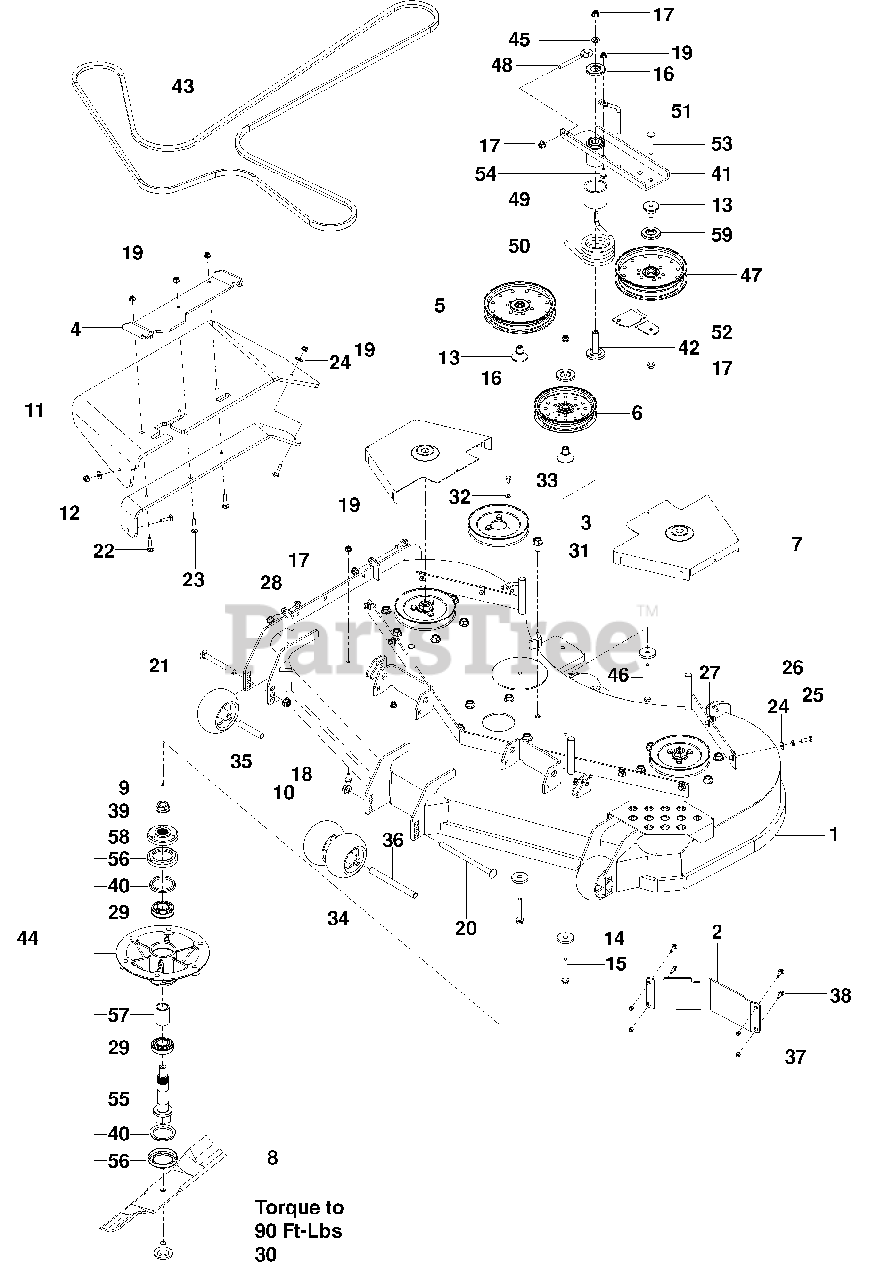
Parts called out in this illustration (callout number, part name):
1	DECK w/ SAFETY DECALS
2	BAFFLE, FLOW DIVERTER
4	BRACKET, CHUTE PIVOT BLK
5	PULLEY, IDLER 7" NARROW
6	PULLEY, IDLER, 6"
7	SHIELD, BELT
8	BLADE, 21"
9	ZERK
10	NUT 1/2-13 HEX FLG NYLOC
11	CHUTE, DISCHARGE
12	BRACKET, CHUTE SUPPORT
13	BEARING, IDLER ARM
14	WASHER, HEAVY
15	SCREW 3/8-16 x 2 3/4 HEX FLG
16	SHIELD, DUST
17	NUT 3/8-16 HEX FLG NYLOC
18	HHFS 5/16-18 x 3/4
19	NUT 5/16-18 HEX FLANGE NYLOC
20	BOLT 1/2-13 x 8 RD HD
21	BOLT 1/2-13 x 4 3/4 RD HD
22	BOLT 5/16-18 x 1 1/2 RD HD
23	BOLT 5/16-18 x 1 1/4 RD HD
24	WASHER 5/16 STD FLT
25	HCS 5/16-18 x 1
26	WASHER 5/16 SLW
27	RETAINER, U TYPE
28	SCREW 3/8-16 x 1 HEX FLG
30	BLADE BOLT
31	SCREW 1/2-13 x 1 HEX FLG
32	WASHER 5/16 DISC SPRING
33	BOLT 5/16-18 x 1/2 HEX NYLOC
34	ROLLER, GAUGE
35	TUBE, ROLLER AXLE
36	SCREW 3/8-16 x 1 1/2 HEX HD
37	NUT 1/4-20 HEX NYLOC
38	BOLT 1/4-20 x 3/4 CARRIAGE
39	NUT 3/4-16 FLG
41	ARM, IDLER w/ BRGS, SPACR
42	BEARING, IDLER PIVOT
43	BELT, DECK
44	SPINDLE ASSY
45	WASHER 3/8 THICK
46	BOLT 3/8-16 x 4 1/2 HEX GR 8
47	PULLEY, IDLER 7" WIDE
48	EYEBOLT 3/8 x 4
49	SPACER, IDLER PIVOT
50	SPRING, TORSION
51	KEEPER, BELT
52	GUIDE, BELT
53	BOLT 3/8-16 x 2 1/2 CARRIAGE
54	BOLT 5/16-18 x 1 RD HD
55	SHAFT, SPINDLE
56	CUP, DEBRIS
59	SHIELD, DUST
